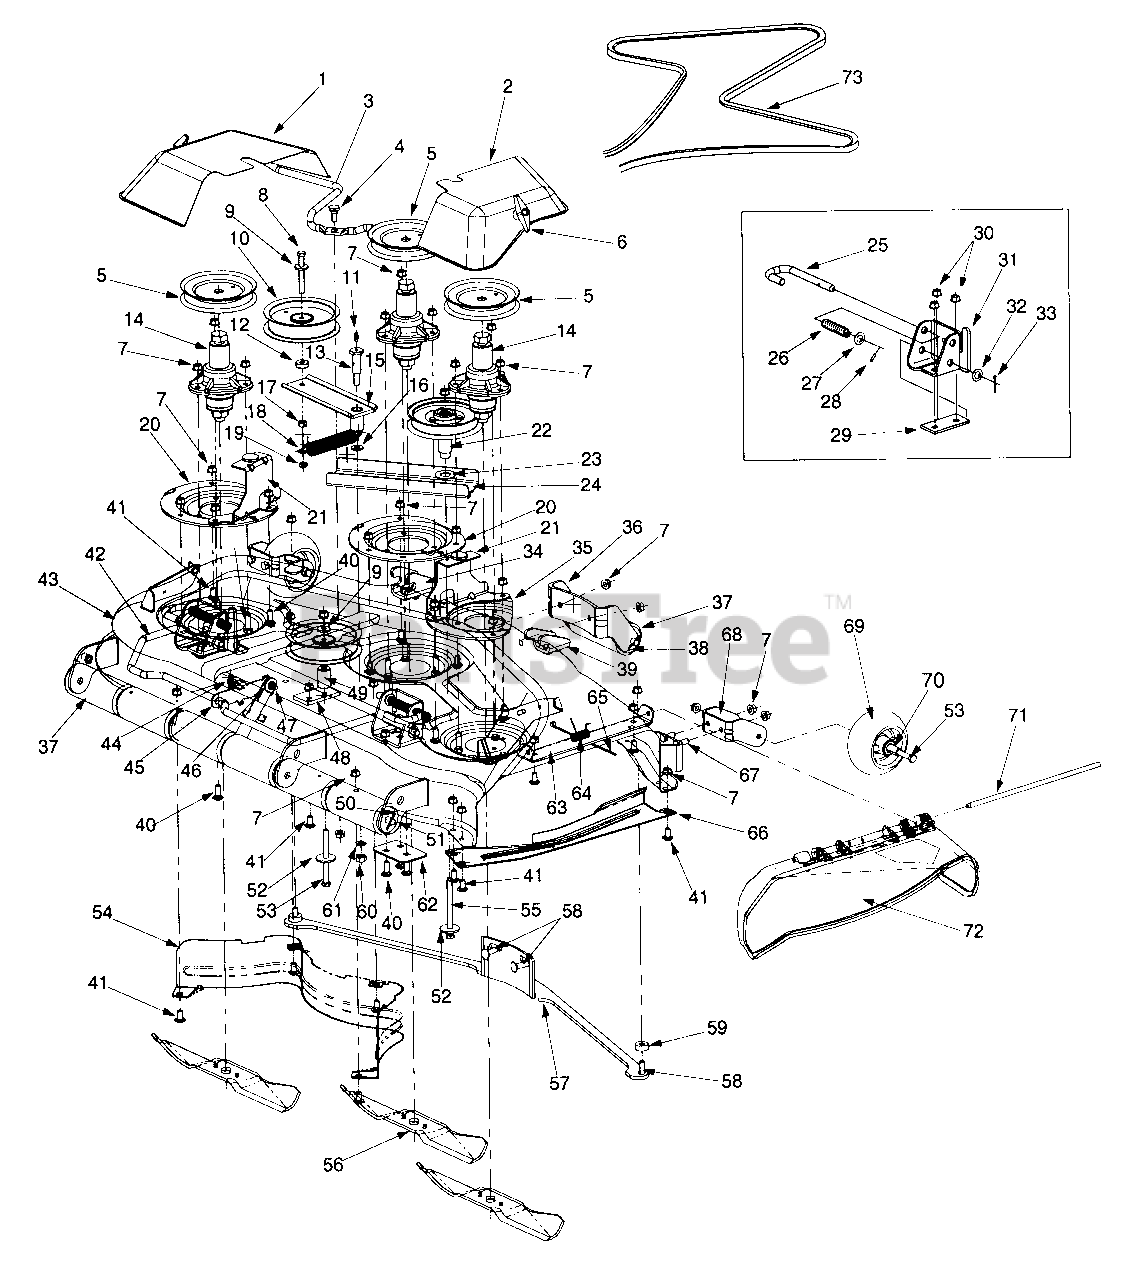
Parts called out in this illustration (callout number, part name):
4	Shoulder Screw 3/8-16
5	Pulley
6	Wingnut Knob
7	Flange Lock Nut 3/8-16
8	Hex Cap Screw 3/8-16 x 3.0
9	Flat Washer .385 ID x 1.0 OD
10	Idler Pulley 5.0
11	Grease Fitting
13	Shoulder Bolt
14	Spindle Ass'y
17	Lock Nut 3/8-16
18	Extension Spring 1.0 OD x 5.78 Lg
19	Jam Nut 3/8-16
23	Flat Washer .78 ID x 1.59 OD
26	Compression Spring
27	Flat Washer .536 ID X .93 QD
28	Spirol Spring Pin
33	Cotter Pin
37	Front Roller
38	Cotter Pin
41	Carriage Bolt 3/8-16 x .75
42	Support Deck Rod
47	Front Roller
50	Cotter Pin
51	Roller Pin
52	Flat Washer
53	Hex Cap Screw 3/8-16 x 4.25
56	Mower Blade
59	Spacer .406 ID x 1.0 OD
60	Hex Nut 7/16-14
61	Lock Washer 7/16
64	Torsion Spring
65	Cable Tie
67	Hex Cap Screw 3/8-16 x .880
71	Hinge Pin
72	Deflector Chute
73	V-Belt
